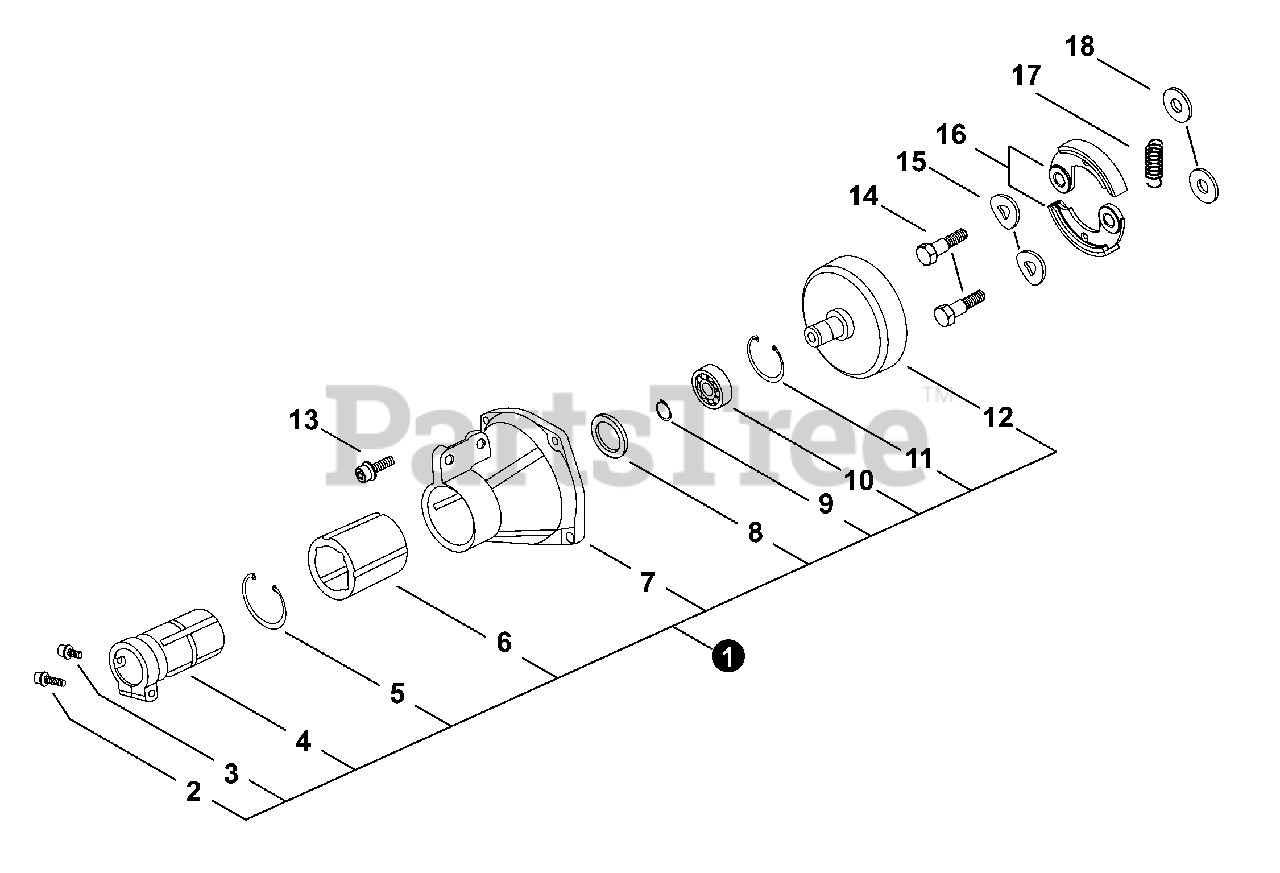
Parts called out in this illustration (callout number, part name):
1	CASE ASSY, CLUTCH
3	SCREW
5	RING, SNAP
6	CUSHION
7	CASE, CLUTCH
9	RING, SNAP
10	BEARING, BALL
11	RING, SNAP
12	DRUM, CLUTCH
13	BOLT
14	BOLT, CLUTCH
15	WASHER 10.2×18×1.0
16	SHOE SET, CLUTCH
17	SPRING, CLUTCH
18	WASHER 8.2×17×1.6
